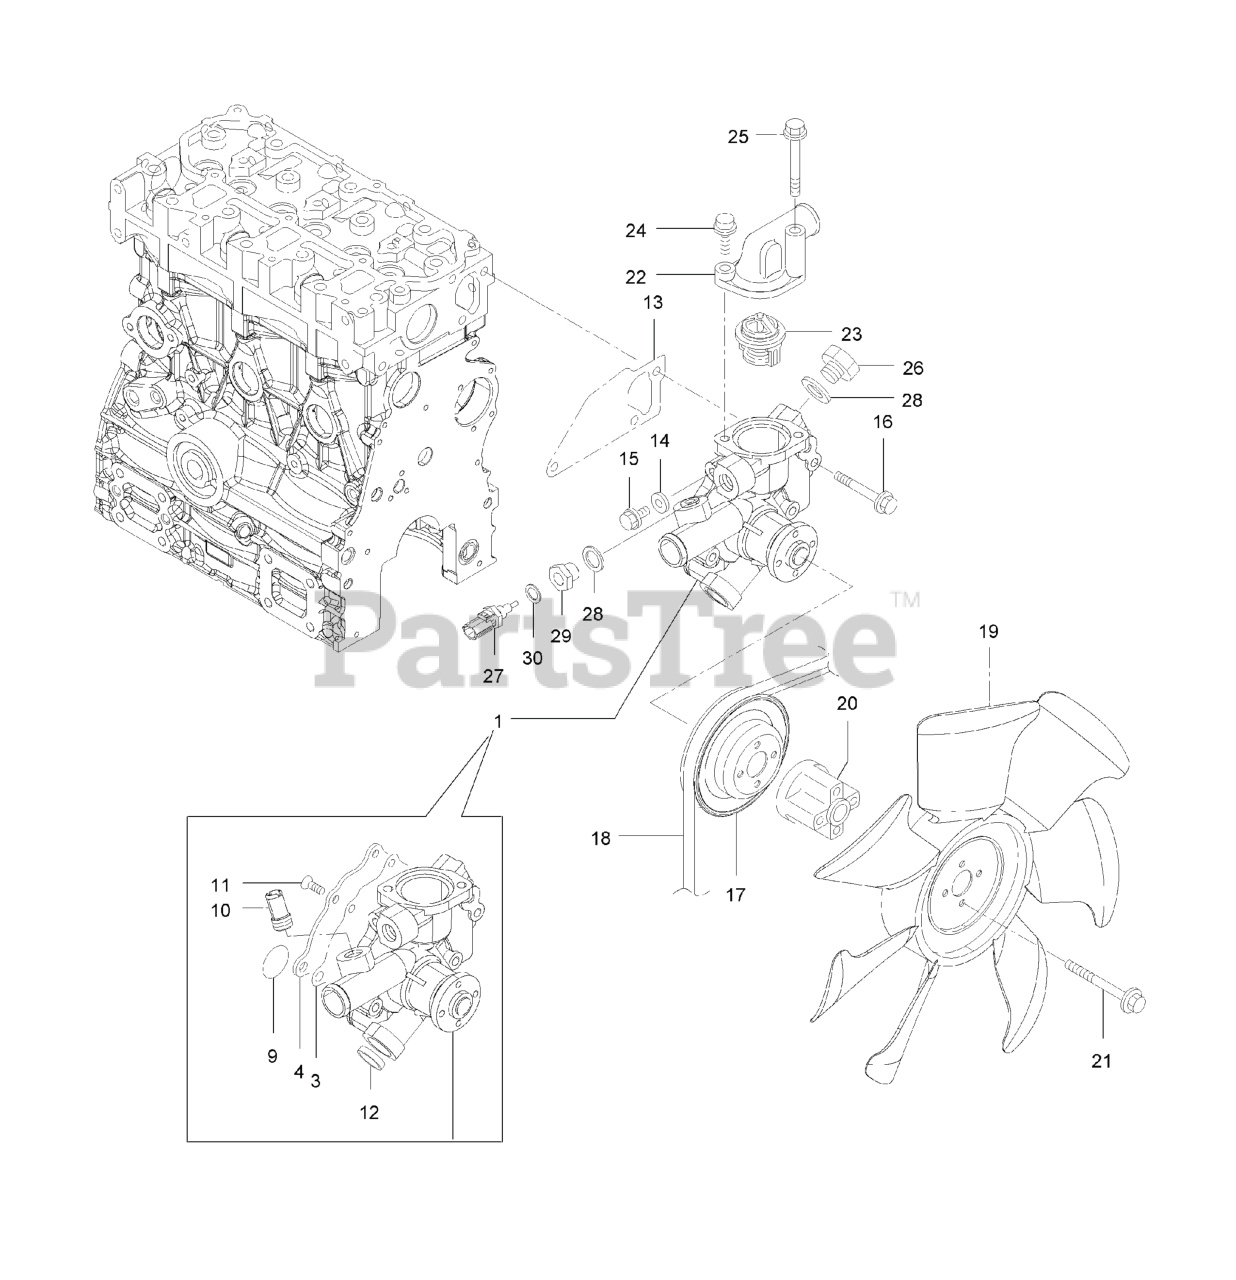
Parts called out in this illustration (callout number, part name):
1	PUMP ASM-WATER
10	JOINT-PIPE
13	GASKET-WATER PUMP
17	V-PULLEY
19	FAN-COOLING 1
20	SPACER-FAN
22	COVER-THERMOSTAT
23	THERMOSTAT
27	SENSOR-THERMOSTAT, CW
30	WASHER-SEAL
